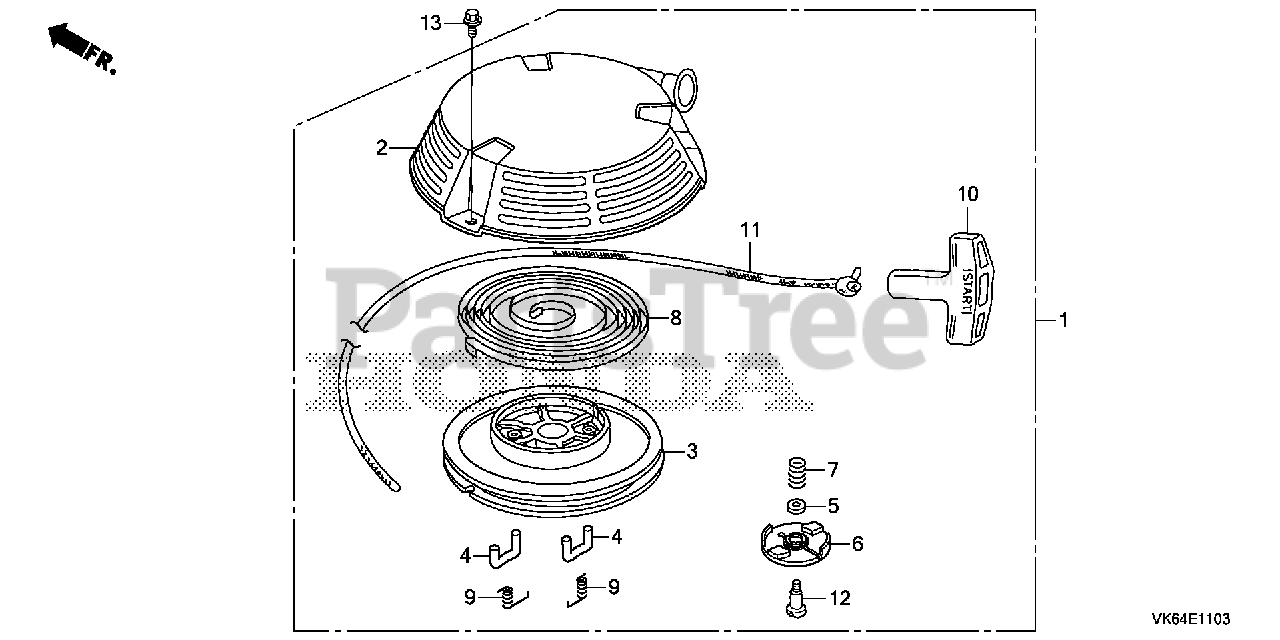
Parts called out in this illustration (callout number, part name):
1	STARTER ASSY., RECOIL *R280* (LONG ROPE) (POWER RED)
2	CASE, RECOIL STARTER *R280* (POWER RED)
3	REEL, RECOIL STARTER (BLACK)
4	RATCHET, STARTER
5	PLATE, FRICTION
6	GUIDE, RATCHET
7	SPRING, FRICTION
8	SPRING, RECOIL STARTER
9	SPRING, RETURN
10	KNOB, RECOIL STARTER
11	ROPE, RECOIL STARTER (LONG TYPE)
12	SCREW, SETTING
13	BOLT, FLANGE (6X8)
